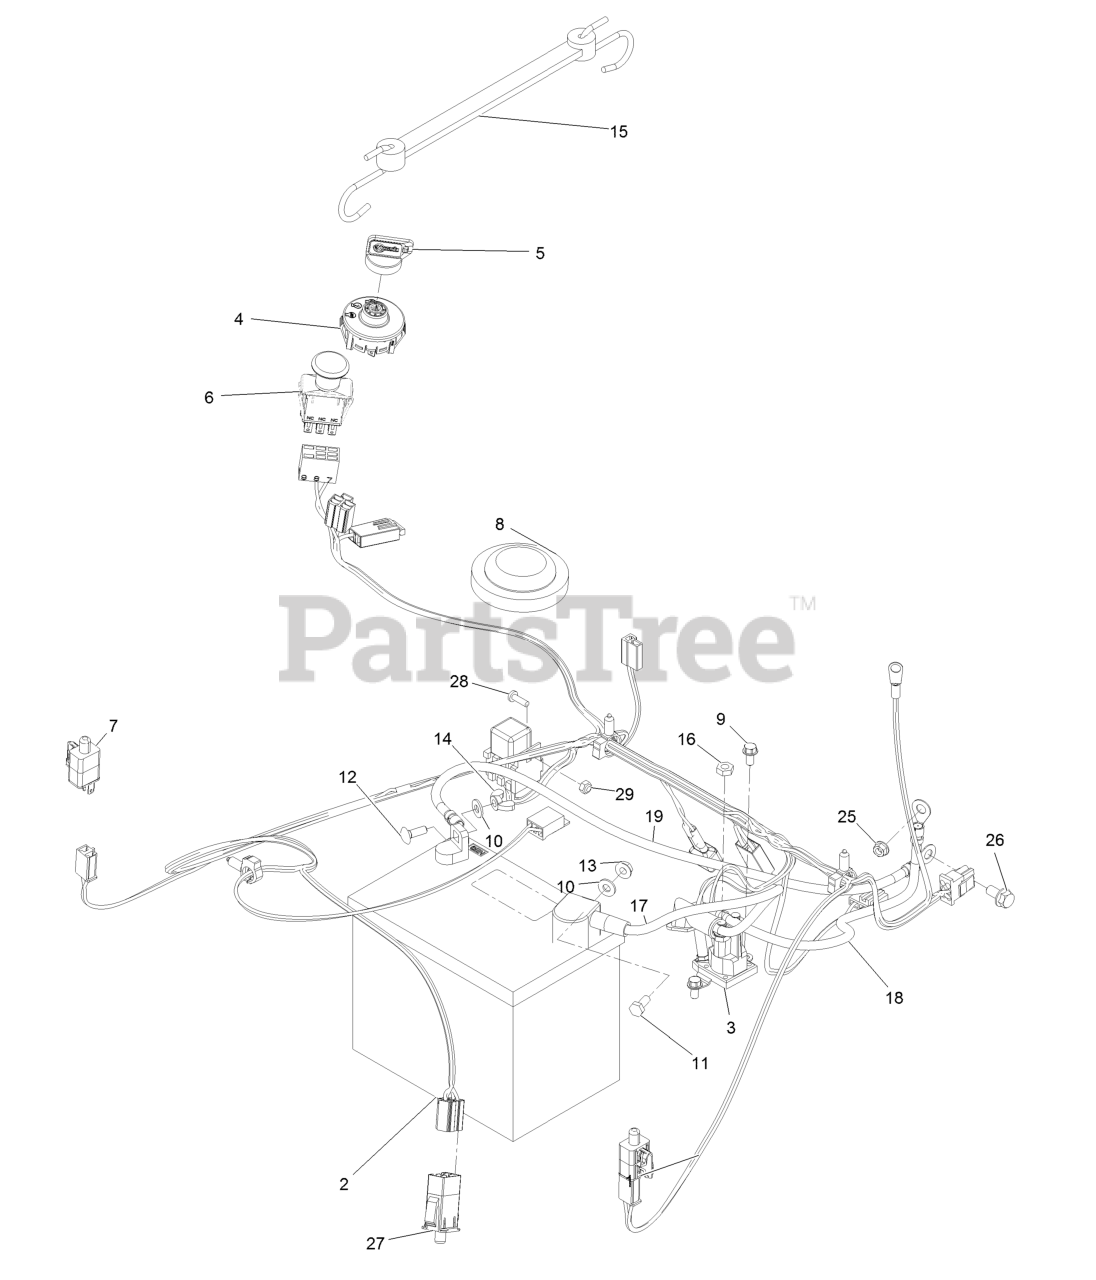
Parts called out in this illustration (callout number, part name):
1	HARNESS-WIRE
2	BATTERY
3	SOLENOID
5	KEY-IGNITION
6	SWITCH-PTO
8	SWITCH-SEAT
9	SCREW-HWH
10	WASHER-FLAT
11	SCREW-HH
12	BOLT-CARR
14	NUT-WING
15	HOLDDOWN-BATTERY
16	NUT-JAM
17	CABLE-BATTERY, RED
18	CABLE-BATTERY, POSITIVE
19	CABLE-BATTERY, BLACK
26	SCREW-HHF
27	SWITCH-DELTA
28	SCREW-PPH
29	NUT-LOCK, NI
